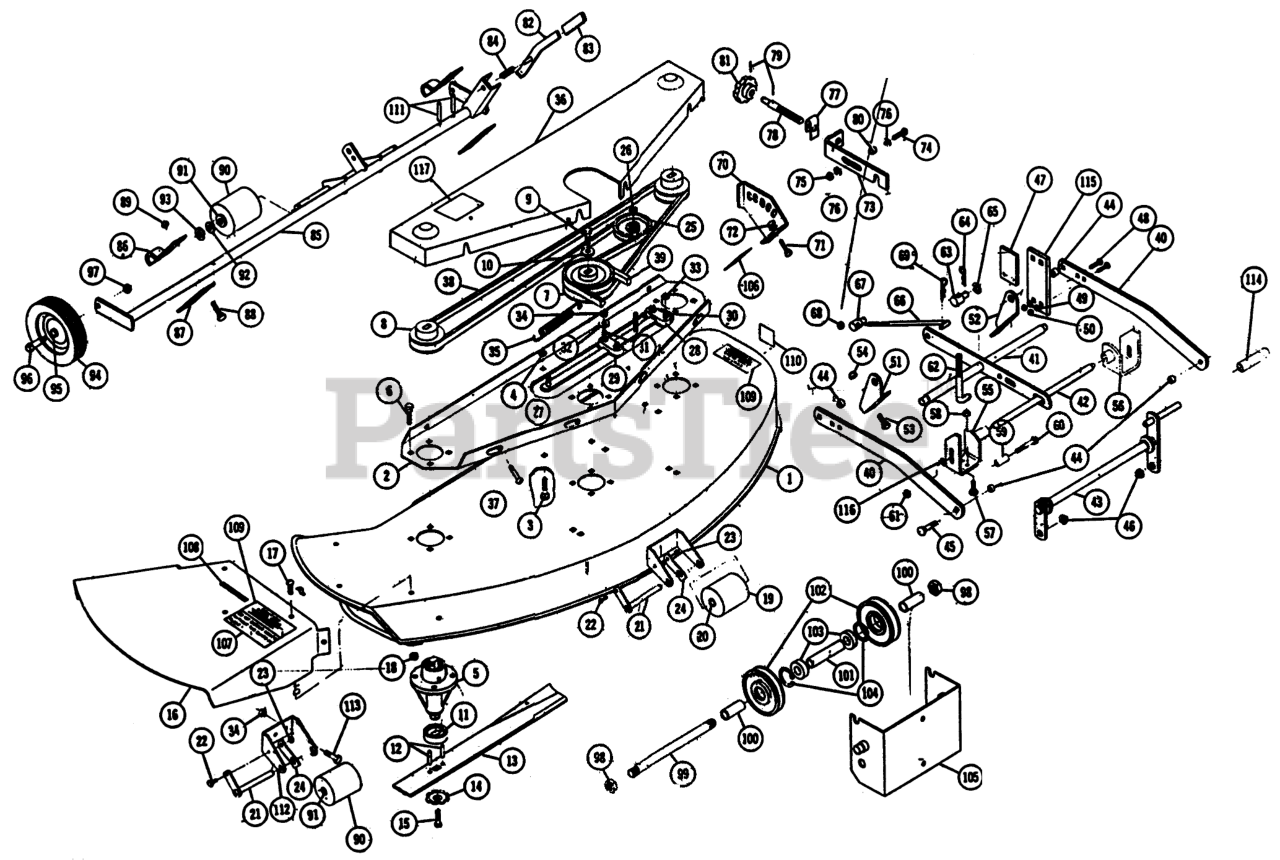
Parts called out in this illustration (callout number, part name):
1	Deck
2	Support
3	Bolt-3/8-16 x 3/4
4	3/8-16 E.S.
5	Spindle Assy.
6	Bolt 3/8-16 x 3/4 Hex
7	Pulley-Center
8	Pulley-Right & Left
9	Bolt 3/8-16 x 3/4 Hex
10	WASHER
11	CUP-SPINDLE
12	SPIROL ROLL PIN
13	Blade 16"
14	WASHER
15	Bolt 3/8-16 x 7/8
16	Chute Extension
17	Bolt 5/16-18 x 5/8
18	Nut 5/16-18
19	Roller
20	BUSHING
21	Roller Shaft
22	Bolt-1/4-20 x 5/8
23	Nut-Nylok
24	SPRING ROLLER STOP
25	Pulley-Idler
26	3/8-16 E.S.
27	ASSY BAR IDLER SUPPO
28	Side Block
29	SLIDE
30	Bolt-5/16-18 x 1/4
31	Bolt-5/16-18 x 1 1/2
32	Washer
33	Nut 5/16-18
34	Nut-Nylok
35	SPRING R
36	Cover
37	Bolt 1/4-20 x 3/8
38	V-BELT
39	V BELT
40	Bar Draft
41	Leveler
42	SHAFT-FRONT R
43	Hitch Assy.
44	SPACER
45	Bolt-3/8-16 x 1
46	LOCKNUT-FLANGE
47	BUMPER
48	Bolt-5/16-18 x 1 1/2
49	Washer
50	Nut-Nylok
51	Bracket-R.H.
52	Bracket-L.H.
53	Bolt-3/8-16 x 3/4
55	Bracket-RH Front
56	LH FT DECK BRKT A R
57	Bolt-3/8-16 x 3/4
59	SPACER-BEARING
60	Bolt-7/16-14 x 1 3/4
61	Nut, 7/16-14
62	LIFT ROD
63	ROD-TRUNNION LIFT
64	Hairpin
65	Washer
66	ROD-LEVELER
67	TRUNNION-LIFT
68	3/8-16 E.S.
69	Hairpin
70	LH QUADRANT R
71	Bolt 3/8-16 x 1
72	3/8-16 E.S.
73	Hitch Adjustment Link
74	Bolt 3/8-16 x 1
76	Washer
77	Detent Spring
78	HITCH ADJ SCREW
79	PIN-ROLL
80	SPACER
81	KNOB-ADJUSTMENT
82	Lever
84	Spring
85	Support Assy.-Gage Wheel
86	Machine Bolt
87	Bar
88	Bolt Carriage 3/8-16 x 1
89	3/8-16 E.S.
90	Roller
91	BUSHING
92	Washer
93	E Ring
94	Wheel
95	BEARING
96	BOLT-SHOULDER
98	Nut-3/4-16 E.S.
99	SHAFT FRONT PULLEY
100	SPACER FRONT PULL R
101	SPACER-FRONT PULLEY
102	V-Pulley
103	BEARING-BALL
104	Ring-Snap
105	Shield Assy.
106	Decal Height Adjustment
107	Decal-Caution
108	Decal Mower Width
109	Decal
110	DECAL-WHEEL HORSE
111	PIN-SPIROL
112	Bracket
113	Bolt Hex 5/16-18
114	GRIP
115	PLATE-BUMPER R
116	Washer
117	Decal Belt Instr.
